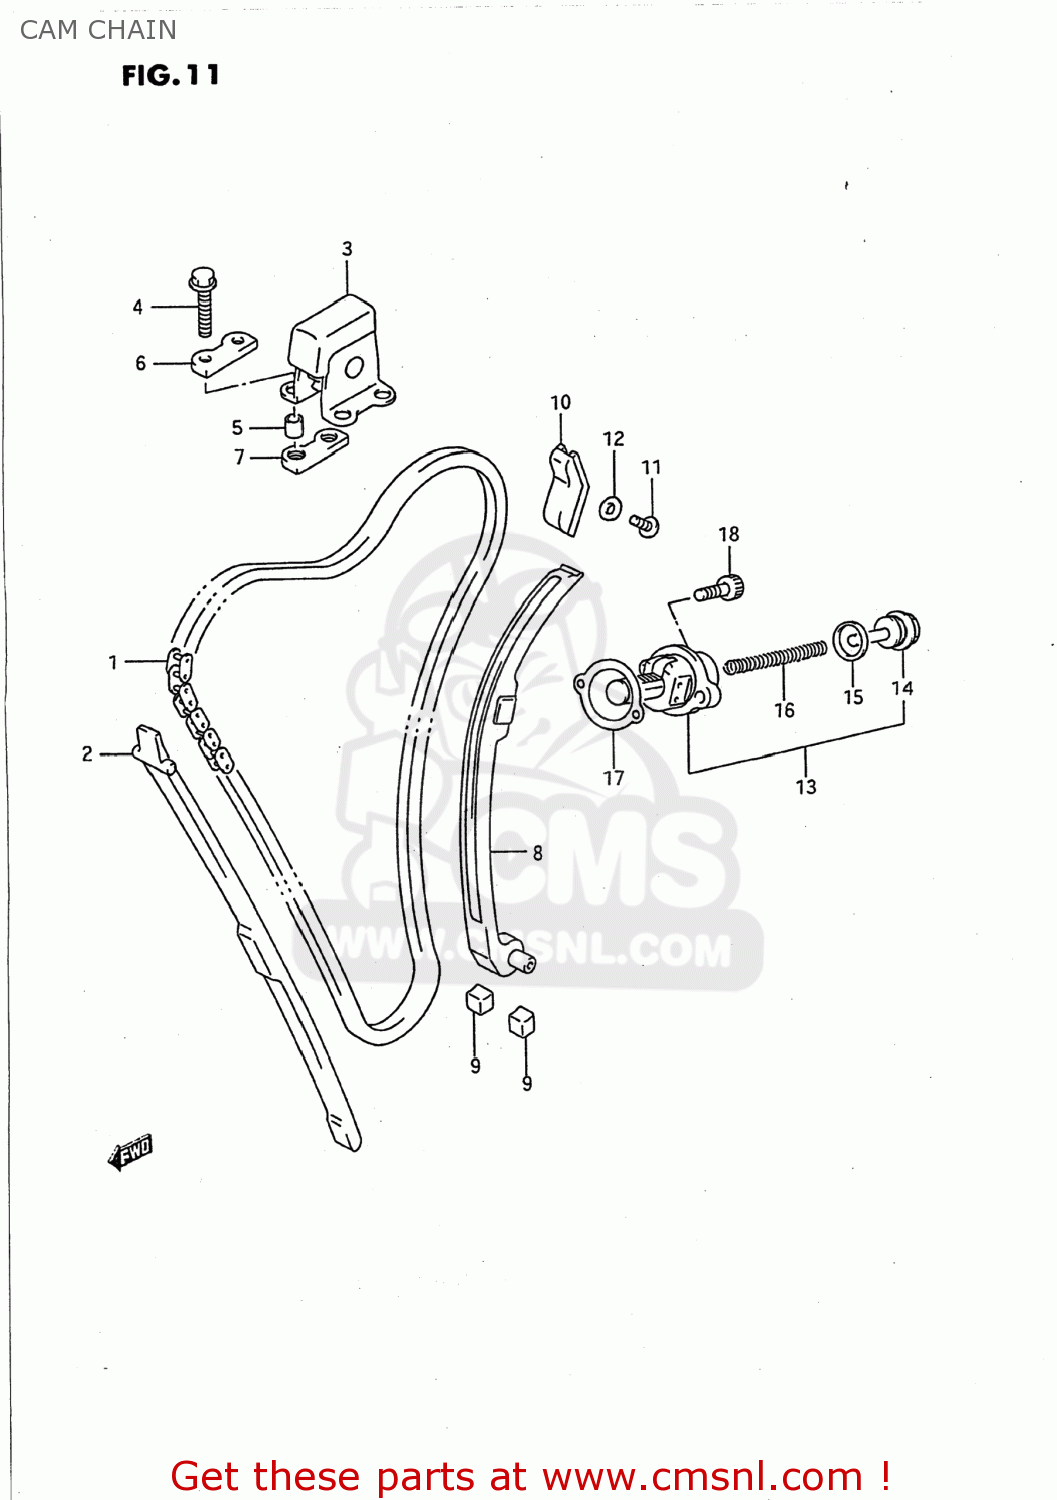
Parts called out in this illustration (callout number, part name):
1	CHAIN,CAMSHAFT DRIVE
2	GUIDE,CAM CHAIN NO.1
3	IDLER,CAM CHAIN
4	BOLT
5	SPACER (6,8X10X9.4)
6	CUSION,IDLER
7	CUSHION,IDLER
8	TENSIONER,CAM CHAIN
9	CUSHION,CAM CHAIN TENSIONER
10	GUIDE,CAM CHAIN NO.2
11	SCREW
12	GASKET(5.8X13X1.2) (NAS)
13	ADJUSTER ASSY,TENSIONER
14	PLUG
15	GASKET (NAS)
16	SPRING
17	GASKET,TENSIONER ADJUSTER (NAS)
18	BOLT
